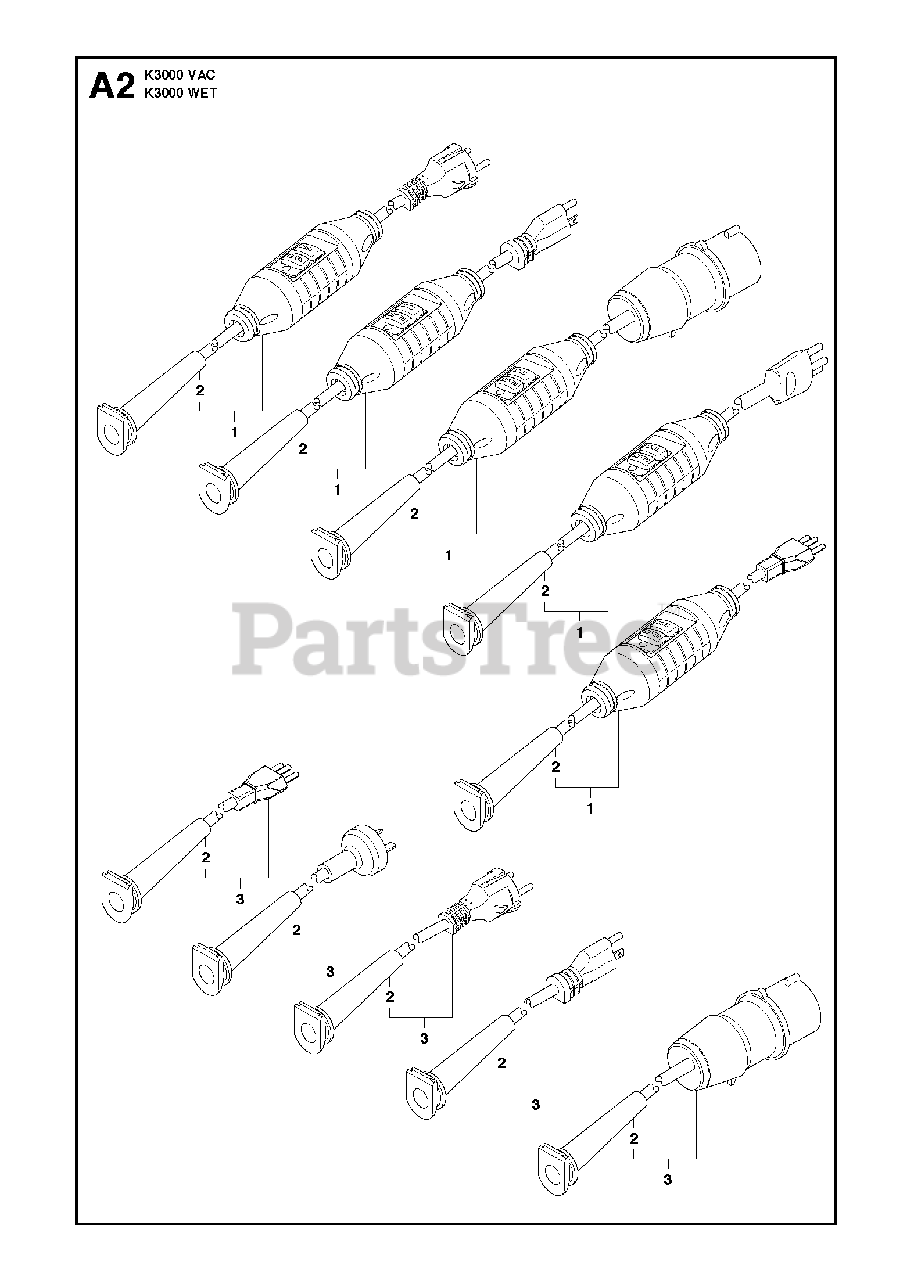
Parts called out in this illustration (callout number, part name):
1	CABLE230V PRCD, incl. 2
1	CABLE110V PRCD, JP, US, incl. 2
1	CABLE110V PRCD, AU, incl. 2
1	CABLE230V PRCD, CH, incl. 2
3	CABLE110V JP, US, incl. 2
3	CABLE110V UK, incl. 2
3	CABLE110V AU, incl. 2
3	CABLE230V CH, incl. 2
